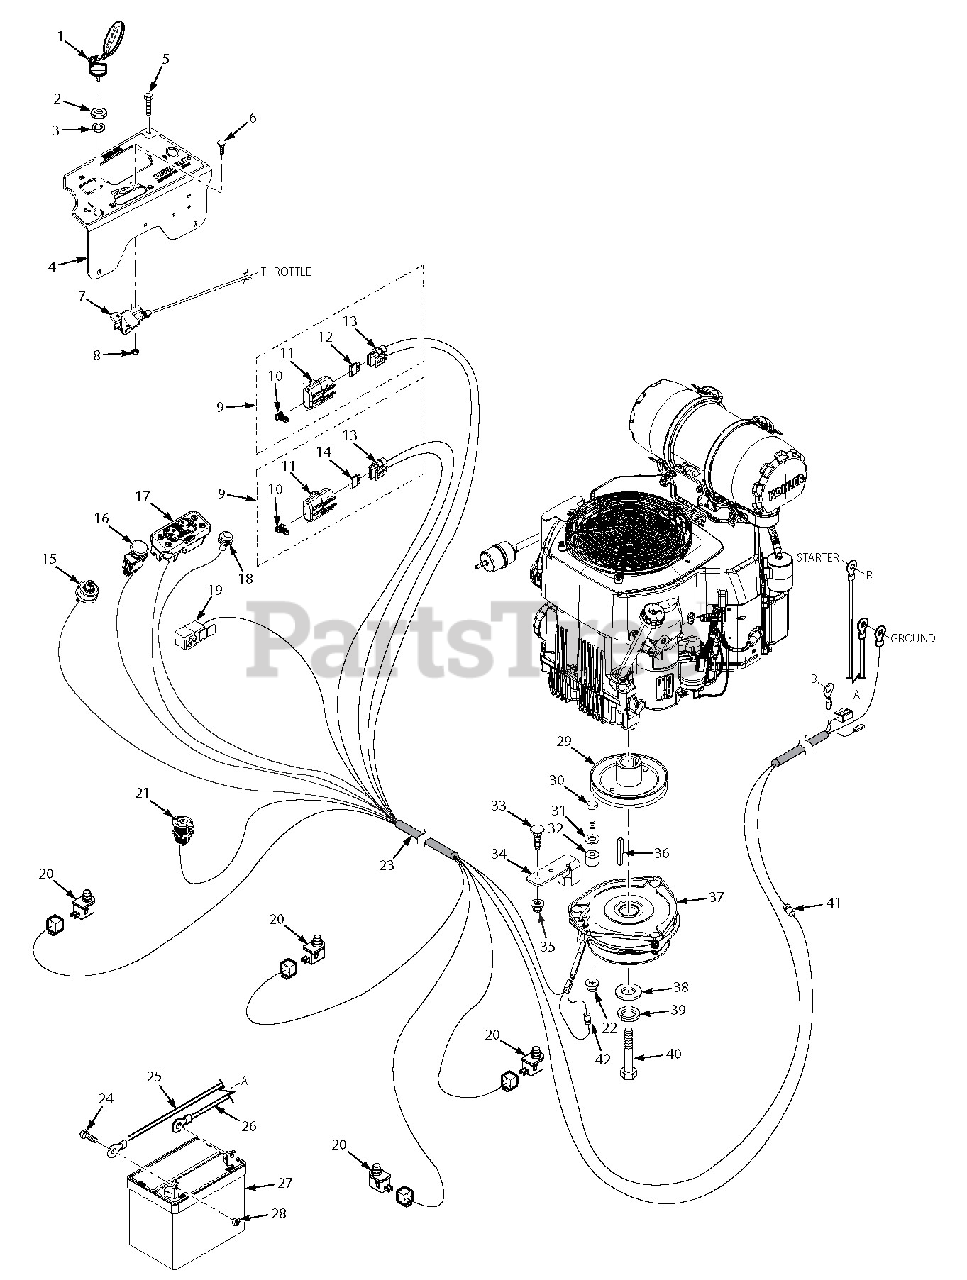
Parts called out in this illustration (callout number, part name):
1	Key, Ignition
2	Nut, Hex 5/8-32
3	Lockwasher, 5/8" Internal
4	Instrument Panel w/Decal
5	Bolt, Hex Head Serrated Flange 1/4-20 x 1/2"
6	Bolt, Carriage #10-24 x 1/2"
7	Throttle Control Cable
8	Locknut, #10-24
9	Single Fuse Assy.
10	Clip, Wire
11	Cover, Sealed Single
12	Fuse, 5 Amp
13	Fuse Holder
14	Fuse, 20 Amp
15	Switch, Starter
16	Switch, PTO
17	Cluster Gauge
18	Indicator Light
19	Relay
20	Switch
21	Power Plug
22	Nut, Elastic Stop 5/16-18
23	Wire Harness, STCII-CV-EFI
24	Bolt, Hex Head 1/4-20 x 1/2"
25	Battery Cable, 25" Red
26	Battery Cable, 27" Black
27	Battery, 350 CCA
28	Nut, 1/4-20 UNC
29	Pulley, 5.75" Dia. - 1.125 Bore
30	Bolt, Hex Head 5/16-18 x 1-1/2"
31	Flatwasher, 5/16-.375 x .875 x .083
32	Bushing, UHMW
33	Bolt, Carriage 5/16-18 x 3/4"
34	Anti-Rotation Bracket
35	Nut, Flange Elastic Stop 5/16-18
36	Key, 1/4 x 1/4 x 3-1/2"
37	Clutch, GT3.5 - 1.125 Bore
38	Flatwasher, 7/16-.469 x 1.75 x .25
39	Lockwasher, 7/16" Spring
40	Bolt, Hex Head 7/16-20 x 2-1/4" w/Patch
41	Diode
42	Diode, 600V - 6A
